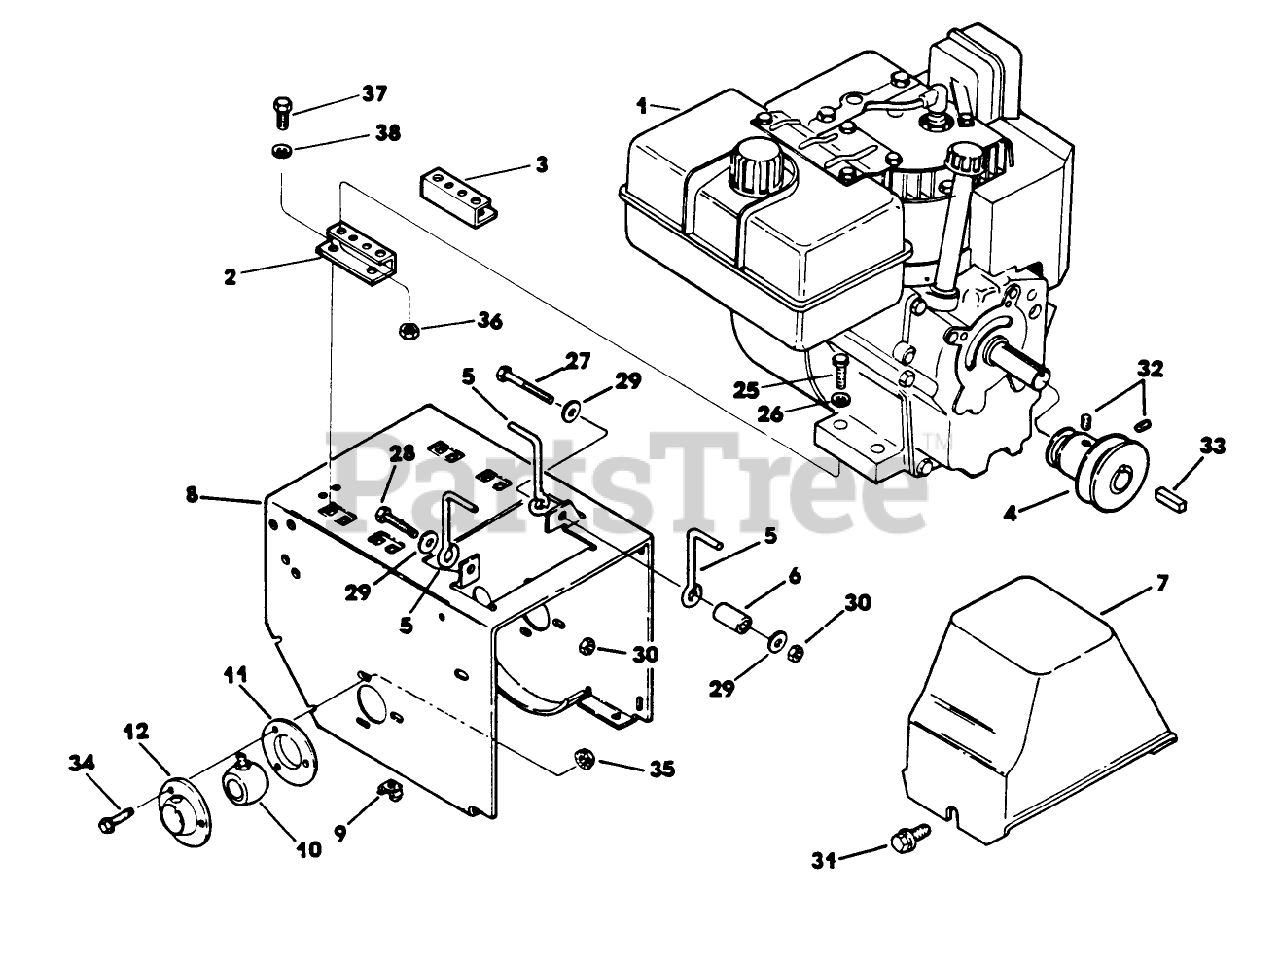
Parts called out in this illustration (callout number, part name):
1	Engine-10 HP Tecumseh Snow King w/ 18w Alternator
1	Engine-8 HP Tecumseh Snow King w/ 18w Alternator
1	Engine-5 HP Tecumseh Snow King
2	ADAPTOR-ENGINE RH
4	PULLEY-CRANKSHAFT
5	GUIDE-BELT
32	SET SCREW
37	SCREW - HEX
